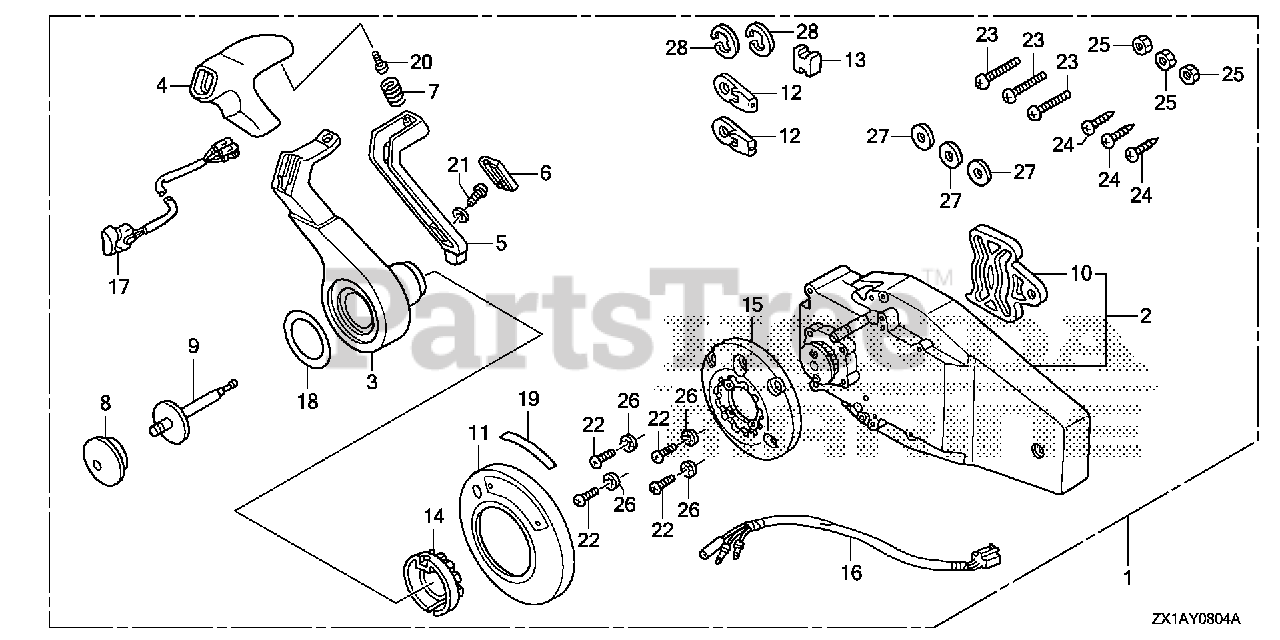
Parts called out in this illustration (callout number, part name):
1	BOX KIT, R. REMOTE CONTROL (FLUSH MOUNT)
2	HOUSING ASSY., R. (INNER) (FLUSH MOUNT)
3	HANDLE, REMOTE CONTROL
4	COVER, GRIP
5	ARM, NEUTRAL LOCK
6	COVER, LOCK ARM
7	SPRING, NEUTRAL LOCK ARM
8	BUTTON, THROTTLE
9	SHAFT, THROTTLE BUTTON
10	PLATE, DWELL
11	COVER ASSY.
12	TERMINAL, CABLE
13	SPACER, CABLE CLAMP
14	HOLDER, NEUTRAL LOCK
15	BASE
16	SUB-HARNESS ASSY., POWER TRIM-TILT (C)
17	SWITCH ASSY., POWER TRIM-TILT (C)
18	MARK, HANDLE FLUSH MOUNT
19	MARK, FLUSH MOUNT
20	SCREW, PAN (5X16)
21	SCREW, TRUSS (4X12)
22	SCREW, PAN (5X30)
23	SCREW, PAN (6X35)
24	SCREW, TAPPING (6X30)
25	NUT, HEX. (6MM)
26	WASHER, LOCK (5MM)
27	WASHER, PLAIN (6MM)
28	E-RING (6MM)
